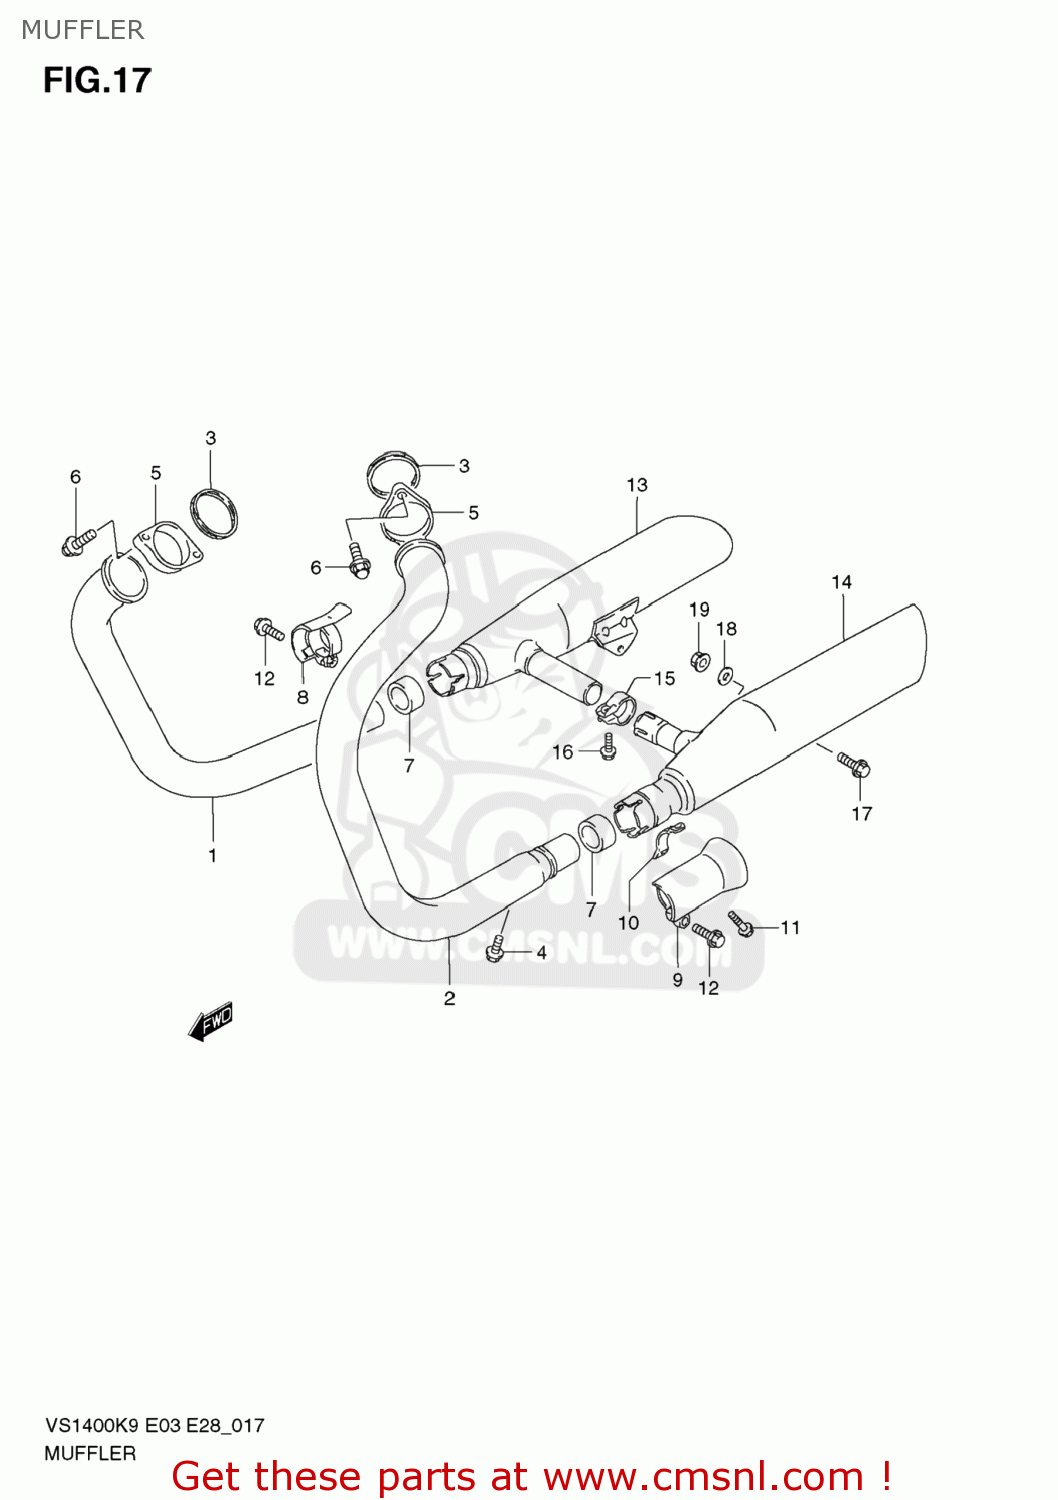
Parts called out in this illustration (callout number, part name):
1	PIPE,EXHAUST,R
2	PIPE,EXHAUST,L
3	GASKET,EXHAUST PIPE (NAS)
4	BOLT
5	CLAMP,EXHAUST PIPE
6	BOLT(8X35)
7	CONNECTOR,MUFFLER
8	CLAMP,CONNECTOR,R
9	CLAMP,CONNECTOR,L
10	CLAMP,MUFFLER COVER
11	BOLT(6X20)
12	BOLT(8X35)
13	BODY,MUFFLER,R
14	BODY,MUFFLER,L
15	CLAMP,EXHAUST COUPLER
16	BOLT
17	BOLT
18	WASHER(8.5X26X1.6)
19	NUT
